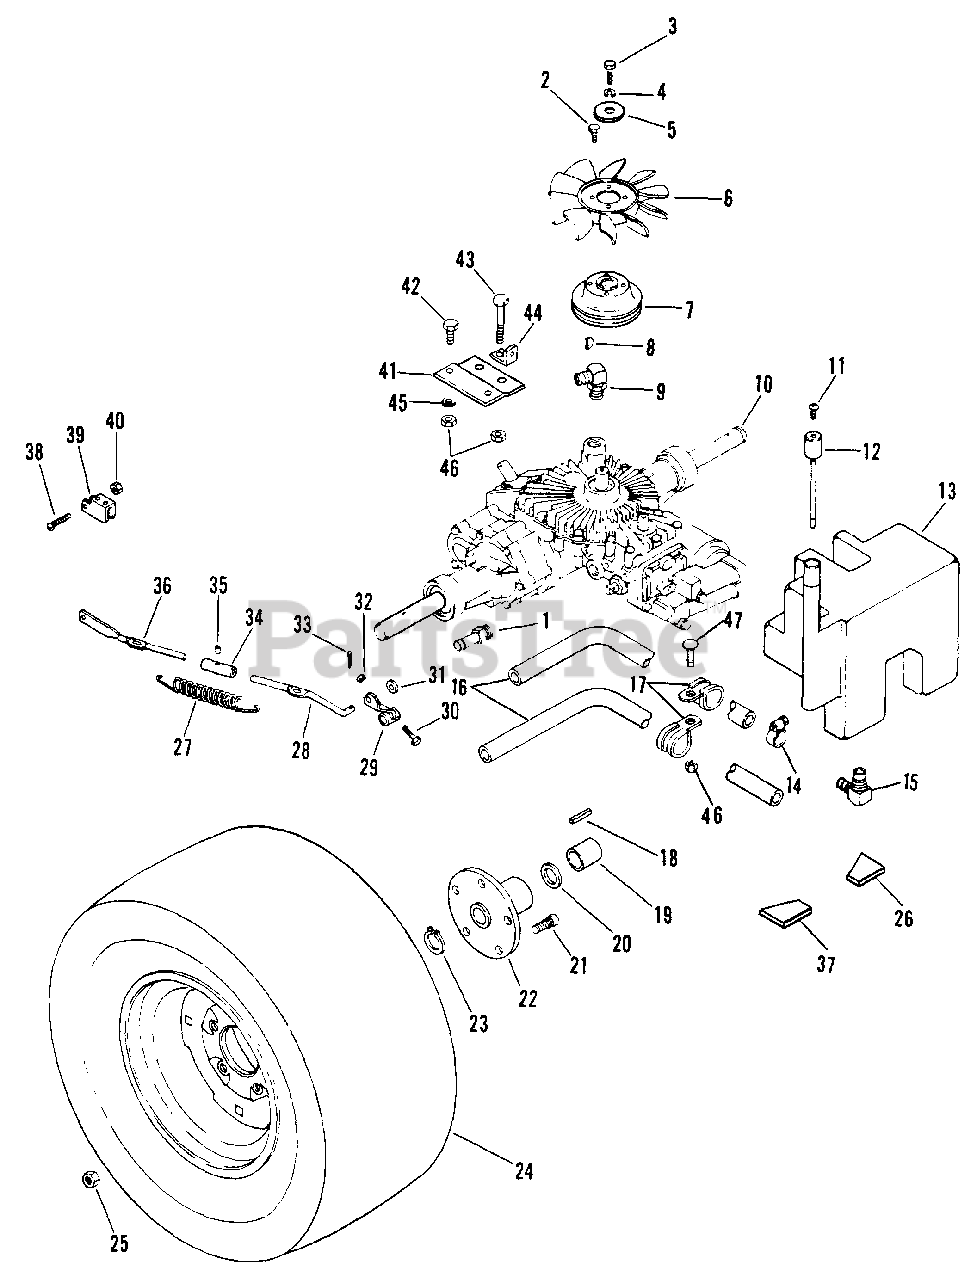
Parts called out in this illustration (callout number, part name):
1	Adapter, #4604-10-10
2	Screw, Mach. 10-24 x .50 PHD
3	Bolt, Hex 1/4-20 x .750
4	Washer, Lock 1/4 Reg.
5	Washer, Special
6	Fan
7	Pulley, Transaxle
8	Key, Woodruff .187 x .625 Hrd. #61
9	Fitting
10	Transaxle
11	Screw, Vent
12	Dipstick
13	Tank, Hydraulic
14	Clamp, .88 DIA. Hose
15	Fitting, O-Ring Barb S/A
16	Hose, Hydraulic
17	Clamp, Steel 1.00
18	Key, Straight
19	Bushing, St. 1.44 x 1.01 x 1.92 Stl.
20	Race, Bearing Thrust .095
21	Lug Bolt
22	Hub, Wheel
23	Snap Ring
24	Wheel, 23 x 10.50-12 2-Ply
25	Nut, Lug 7/16-20
26	Pad, Tank L.H.
27	Spring, Extension
28	Front Dump Valve Rod
29	Dump Vavle Arm
30	Bolt, Hex 1/4-20 x 1.00
31	Washer, Flat .406 x .812 x .065
32	Nut, Lock 1/4-20
33	Pin, Cotter .094 x .75
34	Collar
35	Pin, Roll .125 x .625
36	Rear Dump Valve Rod
37	Pad, Tank R.H.
38	Screw, Mach. 10-24 x 1.0 PHCR
39	Latch
40	Nut, Lock 10-24
41	Bracket, Transaxle Mounting
42	Bolt, Hex 3/8-16 x .875
43	Bolt, Hex 3/8-16 x 2.75
44	Spring Anchor
45	Washer, Flat .375 x 1.125 x .065
46	Nut, Lock 3/8-16
47	Bolt, 3/8-16 x 1.00 Rd Hd Sq Nk
